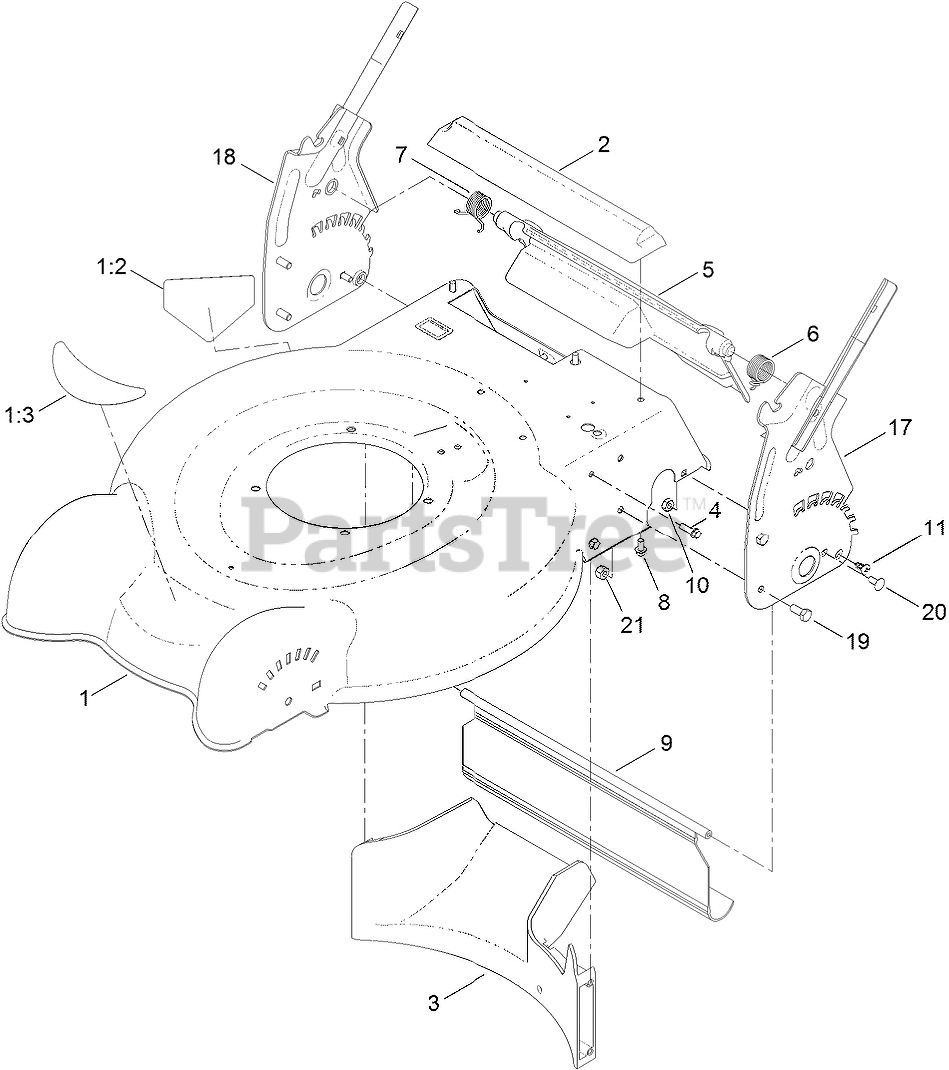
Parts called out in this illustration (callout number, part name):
1	HOUSING ASM
1:2	DECAL-DANGER
1:3	DECAL-DECK
2	CHUTE-REAR
3	BAFFLE-REAR
4	SCREW-HWH
5	Rear Deflector ASM
6	SPRING-TORSION, LH
7	SPRING-TORSION, RH
8	SCREW-PLASTITE
9	SHIELD-TRAILING
10	NUT-LOCK, NI
11	SCREW-PTH
19	SCREW-HH
20	SCREW-CARR
21	NUT-LOCK, NI
